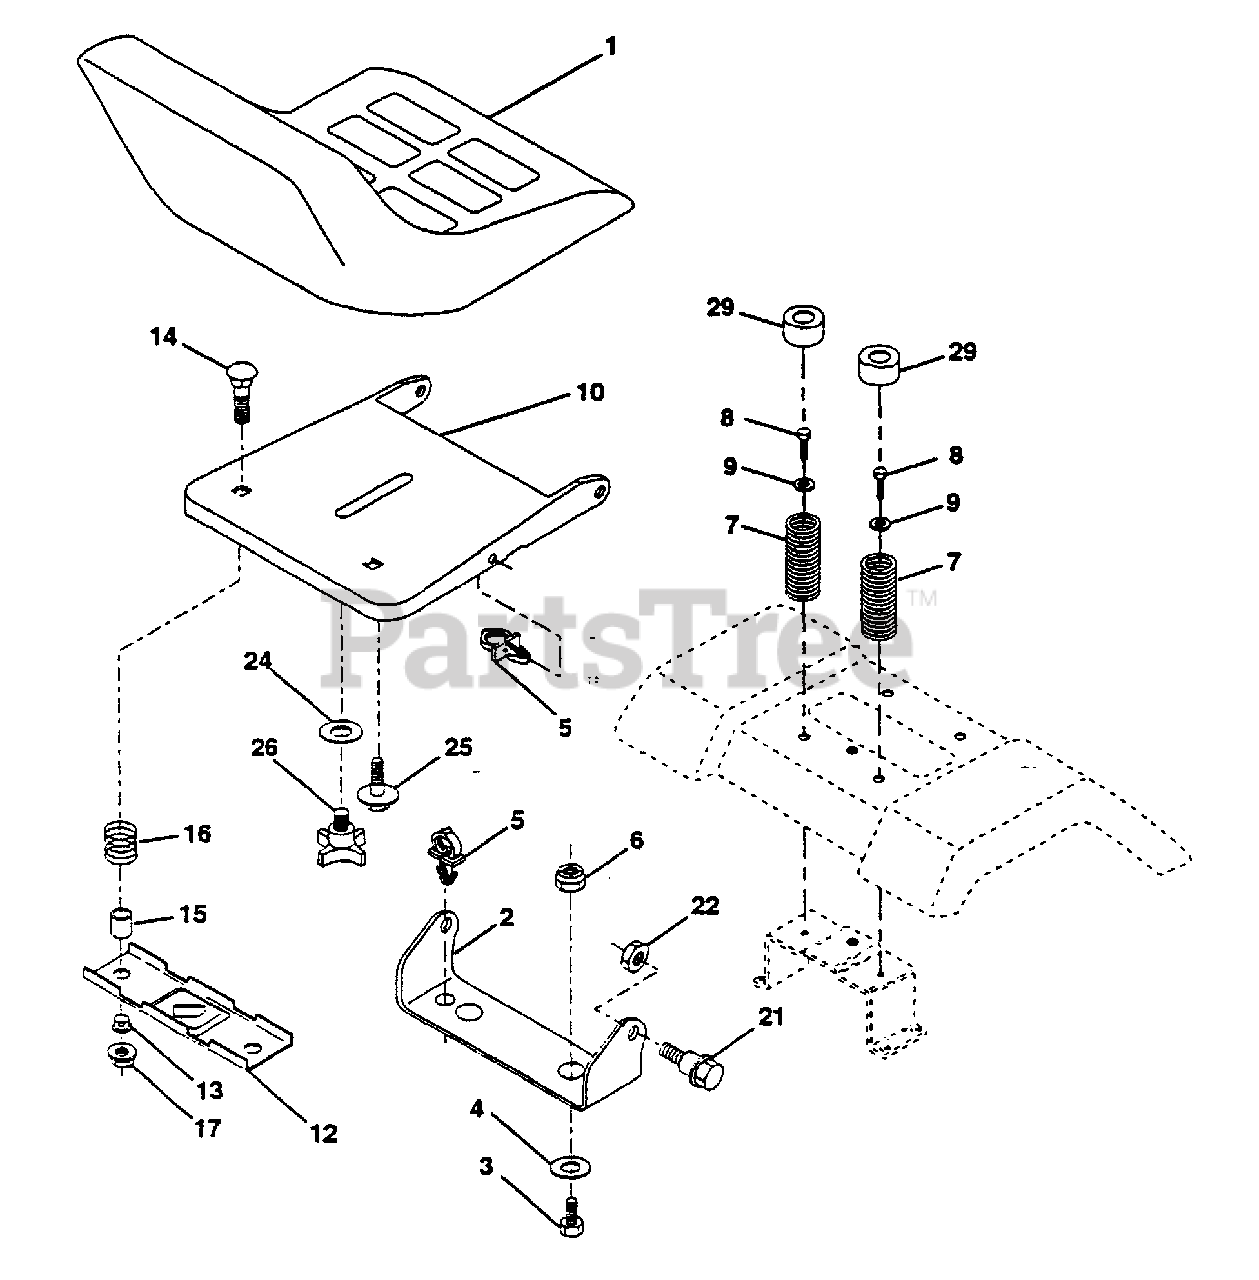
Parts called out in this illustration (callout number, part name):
1	Seat V250 Blk/blk Std
2	Bracket Pivot Seat 8 720
3	Bolt Fin Hex 3/8-16unc X 1
4	Washer 13/32 X 1 X 10 Ga
5	Clip Push-In
6	Nut Crownlock 3/8-16 Unc
7	Spring Seat Cprsn 2 250 Blk Zl
8	Screw Thdrol 3/8-16 X 1 Ty-tt
9	Washer 13/32 X 1 X 14 Ga.
10	Pan Seat
12	Bracket Mounting Switch
13	Bushing Snap Blk Nyl 50 Id
14	Bolt Rdhd Sht Nk 1/4-20x1-3/8
15	Spacer Split 28x 96 Yel Zinc
16	Spring Cprsn 1 27 Blk Pnt
17	Nut Lock 1/4 Lge Fig Gr 5 Zinc
21	Bolt Shoulder 5/16-18 Unc Blkz
22	Nut Hex Lock W/Ins 5/16-18
23	Bjolt Fin Hex 1/2-13 x 7/8 Fr. 5
24	Washer 17/32 X 1-3/16 X 12 Ga.
25	Bolt Shoulder 5/16-18 X 62
26	Washer Lock Hvy HLCLSPR 1/2
29	Cap Spring Seat
